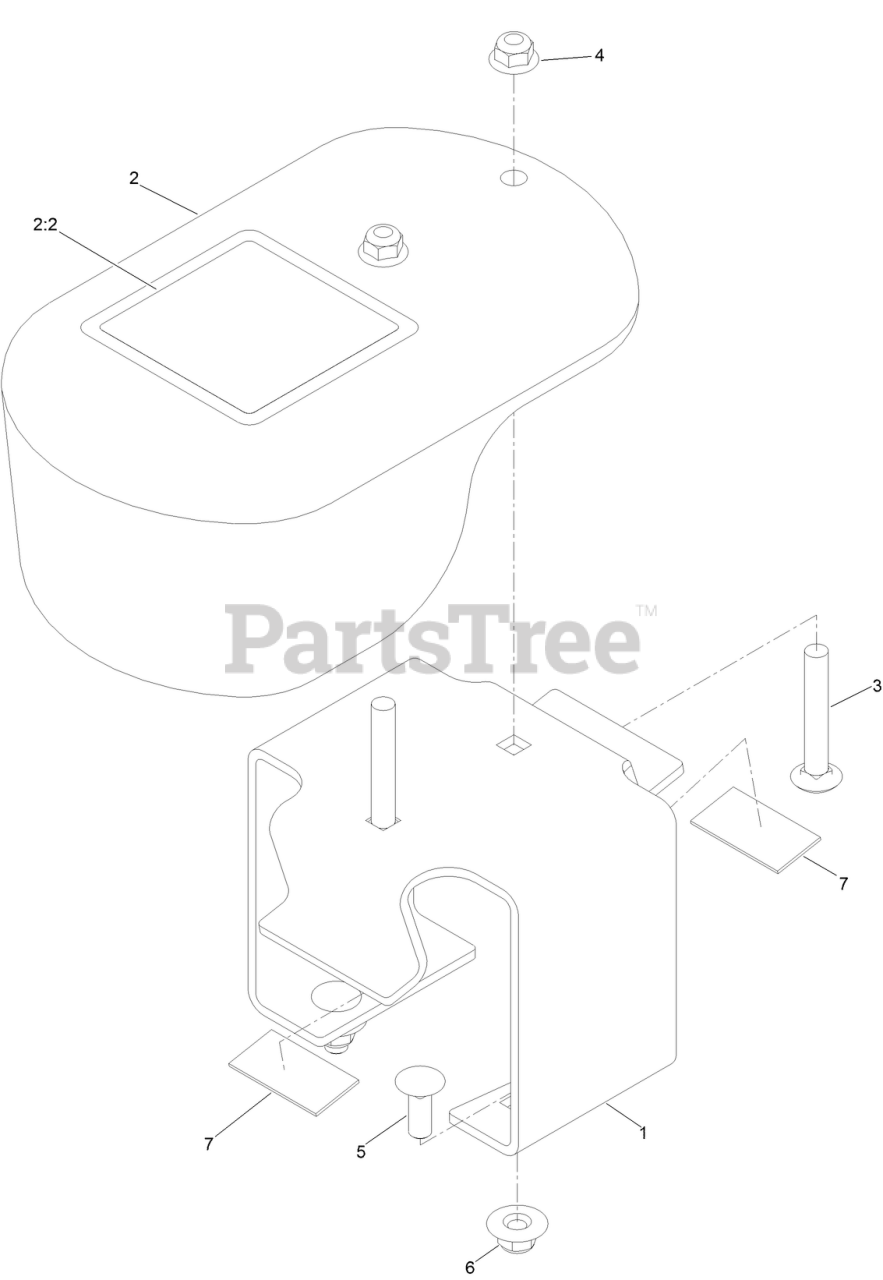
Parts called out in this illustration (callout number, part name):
1	BRACKET-LH CASTER
2	WEIGHT WITH DECAL ASM
2:2	DECAL-WARNING, TRACTION
3	SCREW-CARR
4	NUT-HF, NI
5	SCREW-CARR
6	NUT-FLANGE, NI
7	PAD-RUBBER
